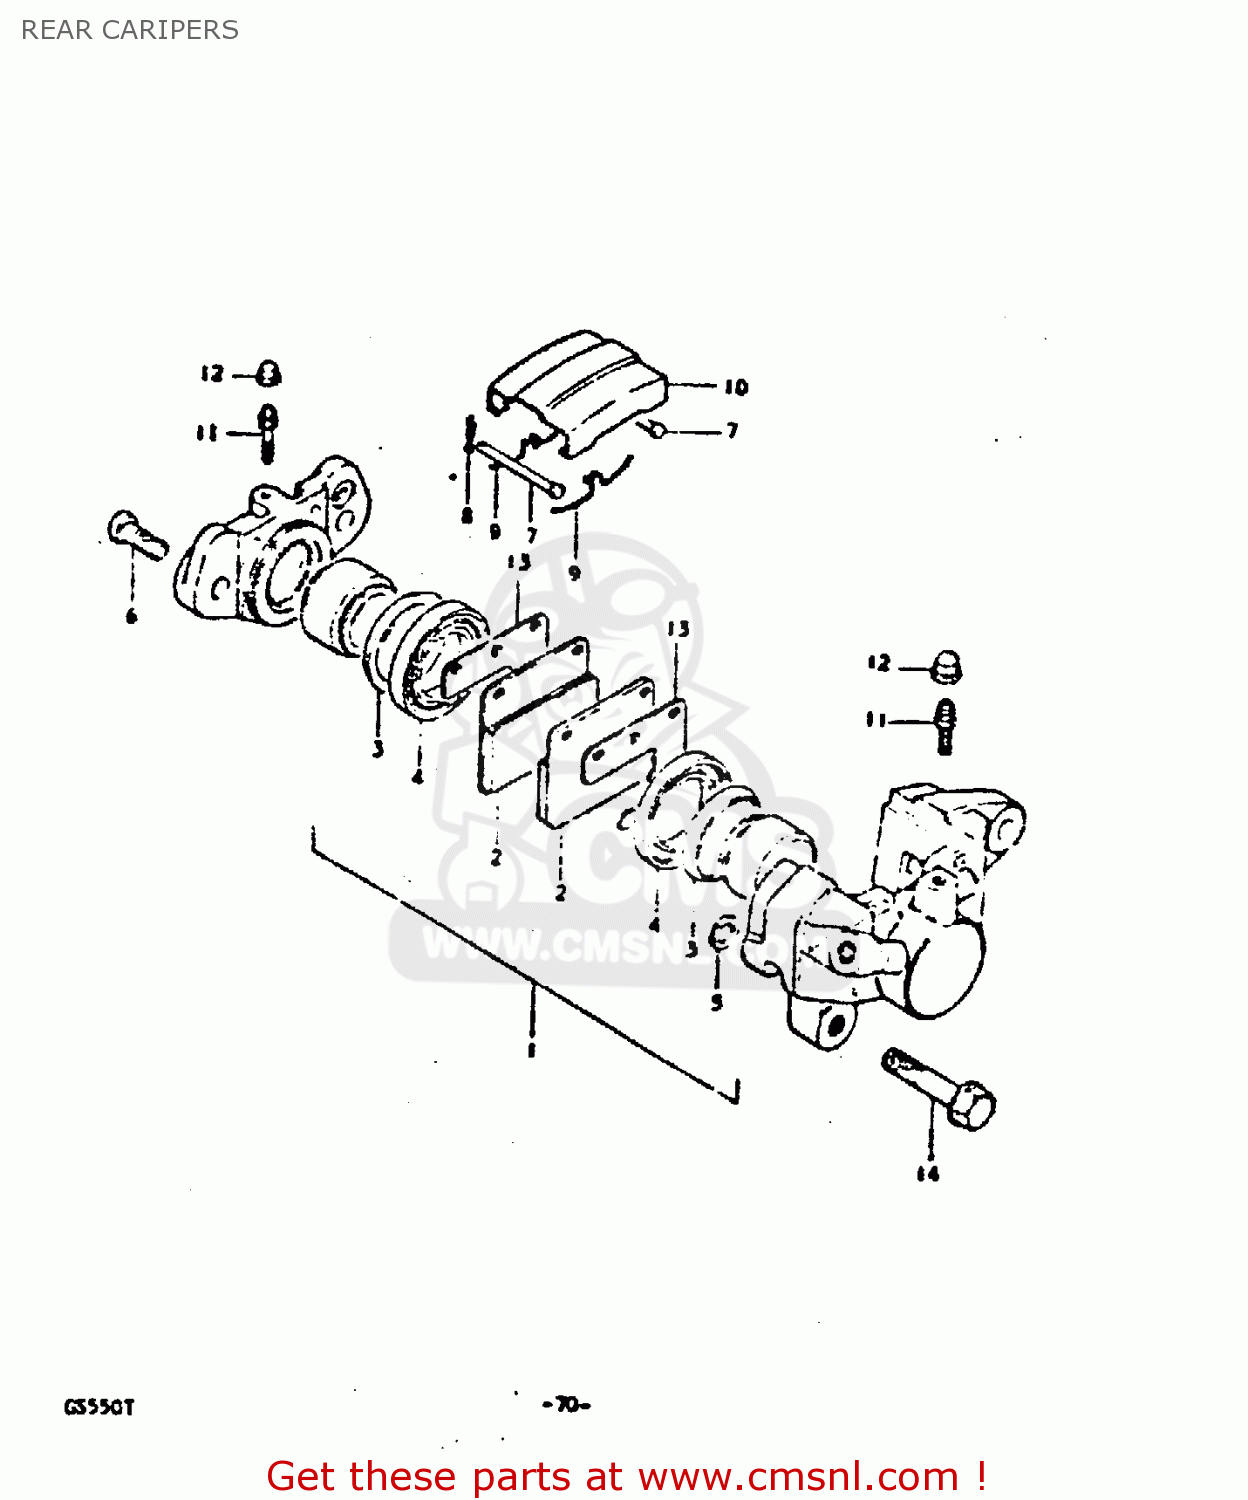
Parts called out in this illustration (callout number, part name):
1	PISTON SET
2	PAD,BRAKE
3	SEAL,PISTON
4	BOOT,PISTON
5	SEAL,PISTON
6	BOLT,HOUSING
7	PIN,PAD
8	CLIP,PAD PIN
9	SPRING
10	COVER,DUST
11	BLEEDER
12	CAP,BREATHER
13	SHIM,RR CALIPER
14	BOLT
